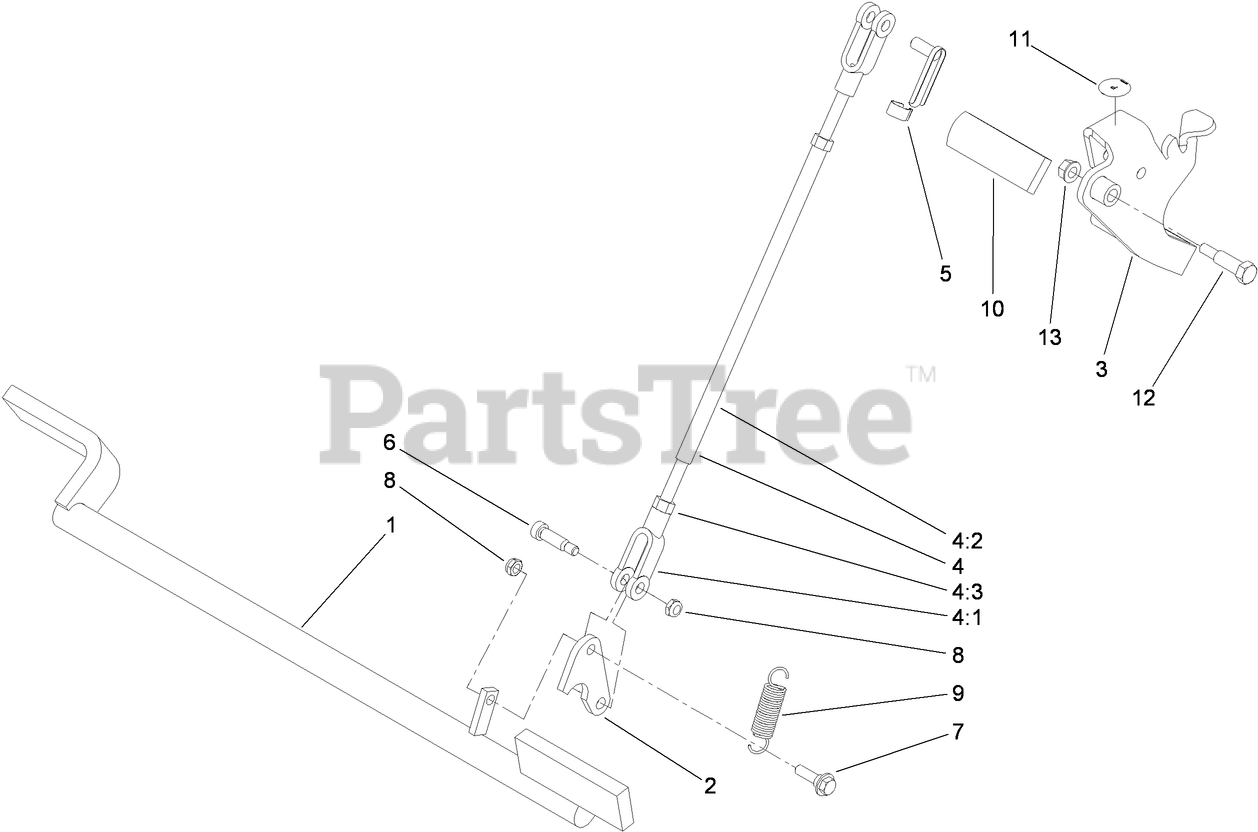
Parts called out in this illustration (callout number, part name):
1	BAR-BRAKE
2	LINK-MOUNTING
3	HANDLE-BRAKE
4	BRAKE ROD ASM
4:1	YOKE-LINKAGE, BRAKE
4:2	LINKAGE-HANDLE, BRAKE
4:3	NUT-HEX
5	Pin-Spring, Clevis
6	BOLT-SHOULDER
7	SCREW-SHOULDER
8	NUT-LOCK, NI
9	SPRING-IDLER
10	GRIP-HANDLE
11	DECAL-PARKING BRAKE
12	SCREW-SHOULDER, HH
13	NUT-HF
